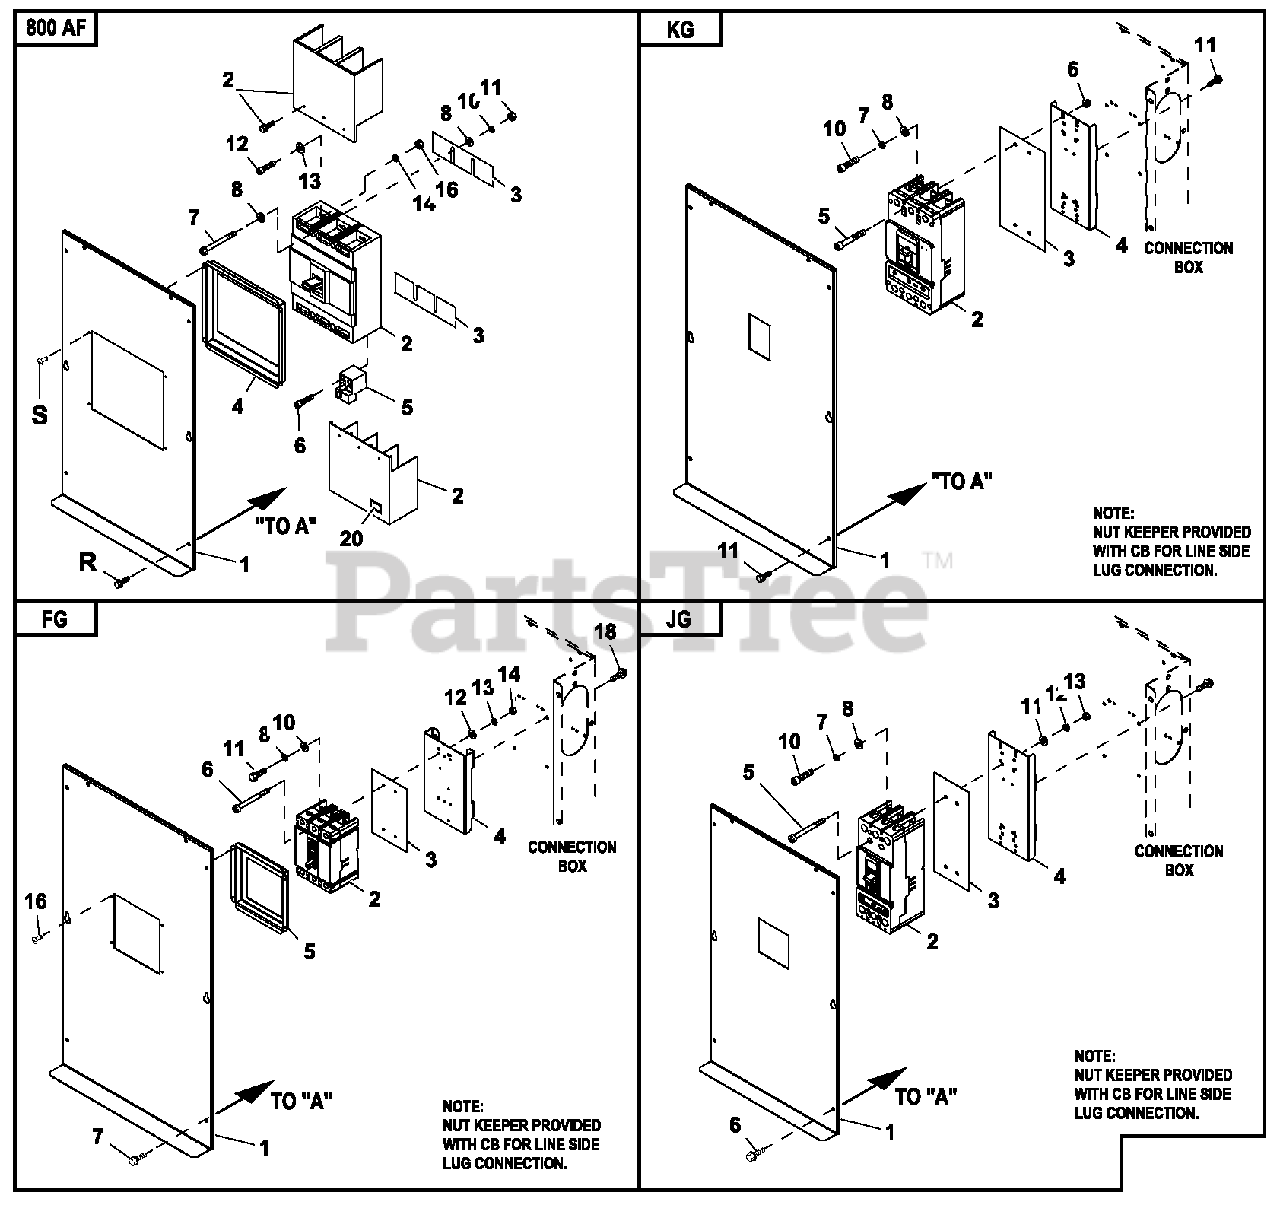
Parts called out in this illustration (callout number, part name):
A	COVER CB G 800AF C5
B	CB 0630A 2P 480V G 800AF
C	INSUL CB800AF
D	COVER CB DISH G 800AF C5
E	LUG SLDLSS 3/0-400X3 MCM AL/CU
F	SCREW SHC M6-1.0 X 50 C8.8
G	SCREW RHM #10-32 X 3-3/4
H	WASHER FLAT #10 ZINC
J	WASHER LOCK #10
K	NUT HEX #10-32 STEEL
L	SCREW SHC M10-1.5 X 25 C12.9
M	WASHER FLAT 3/8-M10 ZINC
N	WASHER LOCK 3/8
P	NUT HEX M10-1.5 G8 YEL CHR
R	SCREW HWHT M6-1 X 16 N WA Z/JS
S	RIVET POP .125 X .275 SS
T	DECAL TERMINAL SHOCK HZD BI
A	COVER CB 3P E KG C5
B	CB 0300 3P 600V E KG LL
C	INSULATOR C B E 3 P KG
D	STANDO F F CB MOUNT CONBOX
E	SCREW SHC M6-1.0 X 50 C8.8
F	NUT FLANGE M6-1.0 NYLOK
G	WASHER LOCK M8-5/16
H	WASHER FLAT 5/16-M8 ZINC
J	SCREW SHC M8-1.25 X 30 C12.9
K	SCREW HWHT M6-1 X 16 N WA Z/JS
A	COVER CB 3P E F G C5
B	CB 0060 3P 600V E F G LL
C	INSULATOR CB 3P E TYPE CC/F G
D	STANDO F F CB BOX CONBOX
E	COVER CB DISH 3P E F G
F	SCREW PPHM #8-32 X 1-3/4 ZINC
G	SCREW HWHT M6-1 X 16 N WA Z/JS
H	WASHER LOCK M5
J	WASHER FLAT #10 ZINC
K	SCREW HHC M5-0.8 X 20 G8.8
L	WASHER FLAT #8 ZINC
M	WASHER LOCK#8-M4
N	NUT HEX #8-32 STEEL
P	RIVET POP .125 X .275 SS
A	COVER CB 3P E JG C5
B	CB 0250 3P 600V E JG LL
C	INSULATOR CB E 3P JG
E	SCREW RHM 1 /4 -2 0X 3
F	SCREW HWHT M6-1 X 16 N WA Z/JS
J	SCREW SHC M8-1.25 X 20 G8
K	WASHER FLAT 1/4-M6 ZINC
L	WASHER LOCK M6-1/4
M	NUT HEX 1/4-20 STEEL
